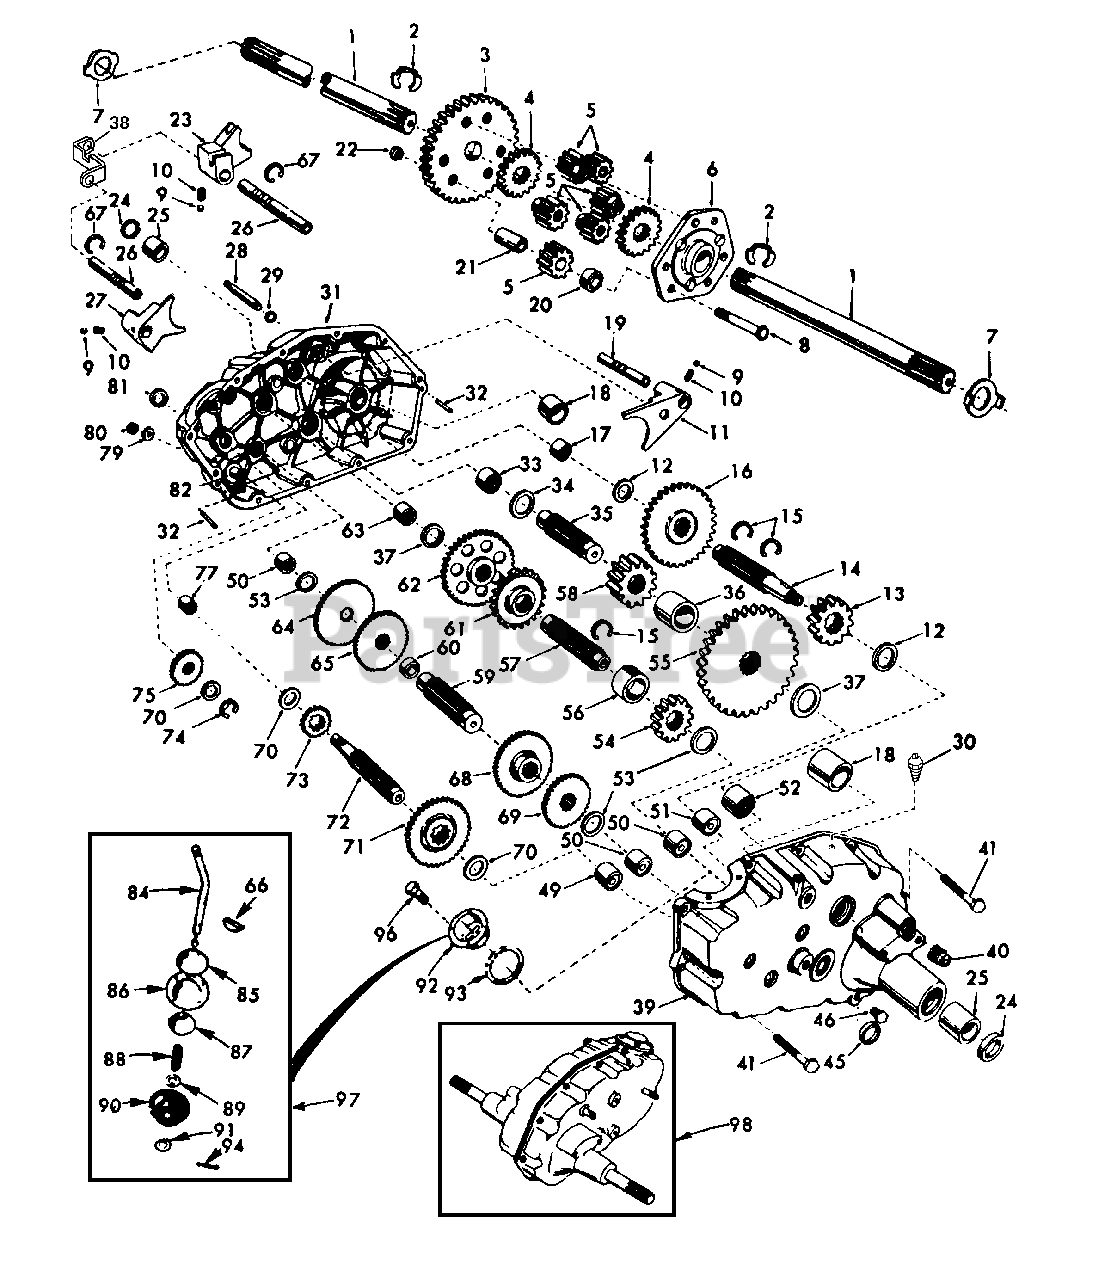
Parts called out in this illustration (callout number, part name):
2	Retaining Ring
3	Final Drive Gear
4	Differential Gear
5	Differential Pinion
6	Differential Carrier
7	Axle Thrust Washer
8	Bolt, Hex Head 3/8-24 x 3-1/4 (1" Thread Length)
9	Steel Ball
10	Spring Shift Fork Detent
11	Shift Fork, High-Low Range
12	Thrust Bearing Race
13	4th Reduction Pinion
14	Shaft, Brake
15	Snap Ring, Crescent Type
16	High-Low Range Gears
17	Needle Bearing
18	Sintered Iron Bearing
19	Shift Fork Shaft, High-Low Range
20	Differential Pinion Spacer
21	Differential Pinion Bushing
22	Gripco Centerlock Nut 3/8-24
23	Shift Fork, R.H.
24	Oil Seal
25	Sintered Iron Bearing
26	Shift Fork Shaft
27	Shift Fork, L.H.
28	Shift Shaft, High-Low Range
29	Oil Seal
30	Pressure Relief Valve
31	Gearcase, Reverse Idler Shaft and Bearings, R.H.
32	Dowel Pin
33	Needle Bearing
34	Thrust Bearing Race
35	4th Reduction Gear Shaft
36	4th Reduction Gear Spacer
37	Thrust Bearing Race
38	Gate, Lower, Shift
39	Gearcase and Bearings, L.H.
40	Pipe Plug 1/2-14 N.P.T.
41	Bolt, Hex 5/16-18 UNC x 1-1/4
45	Oil Seal
46	Pipe Plug 1/4-18 N.P.T.
49	Needle Bearing
50	Needle Bearing
51	Needle Bearing
52	Needle Bearing
53	Thrust Bearing Race
54	3rd Reduction Pinion, Low
55	4th Reduction Gear
56	3rd Reduction Pinion Spacer
57	2nd Reduction Gear Shaft
58	Final Drive Pinion
59	1st Reduction Gear Shaft
60	1st Reduction Shaft Spacer
61	3rd Reduction Pinion High
62	2nd Reduction Gear
63	Needle Bearing
64	Low Speed Gear and 2nd Reduction Pinion Cluster
65	Reverse Gear
66	Key, Hi-Pro 1/8 x 17/32
67	Klip Ring
68	Intermediate Speed Gear
69	High Speed Gear
70	Thrust Bearing Race
71	Intermediate and High Speed Cluster Pinions
72	Input Shaft
73	Low Speed Pinion
74	E-Ring
75	Reverse Idler Gear
77	Needle Bearing
79	Sealing Washer
80	Nut, Hex, Jam 7/16-20
81	Oil Seal
82	Reverse Idler Shaft
84	Gearshift Lever, Bent
85	Gearshift Cap
86	Gearshift Ball Cover and Pin
87	Shift Lever Guide Ball, Keyed
88	Spring
89	Washer 15/32 x 15/16 x 16 Ga.
90	Shift Mechanism Seal
91	Washer 9/16 x 15/16 x 12 Gauge
92	Gearshift Gate and Reinforcement
93	Shift Ball Cover Gasket
94	Cotter Pin 1/8 x 3/4
96	Screw, Hex, Washer, HD.
97	Gearshift Lever Assembly
98	Transaxle, 6 Speed, Complete Assembly
